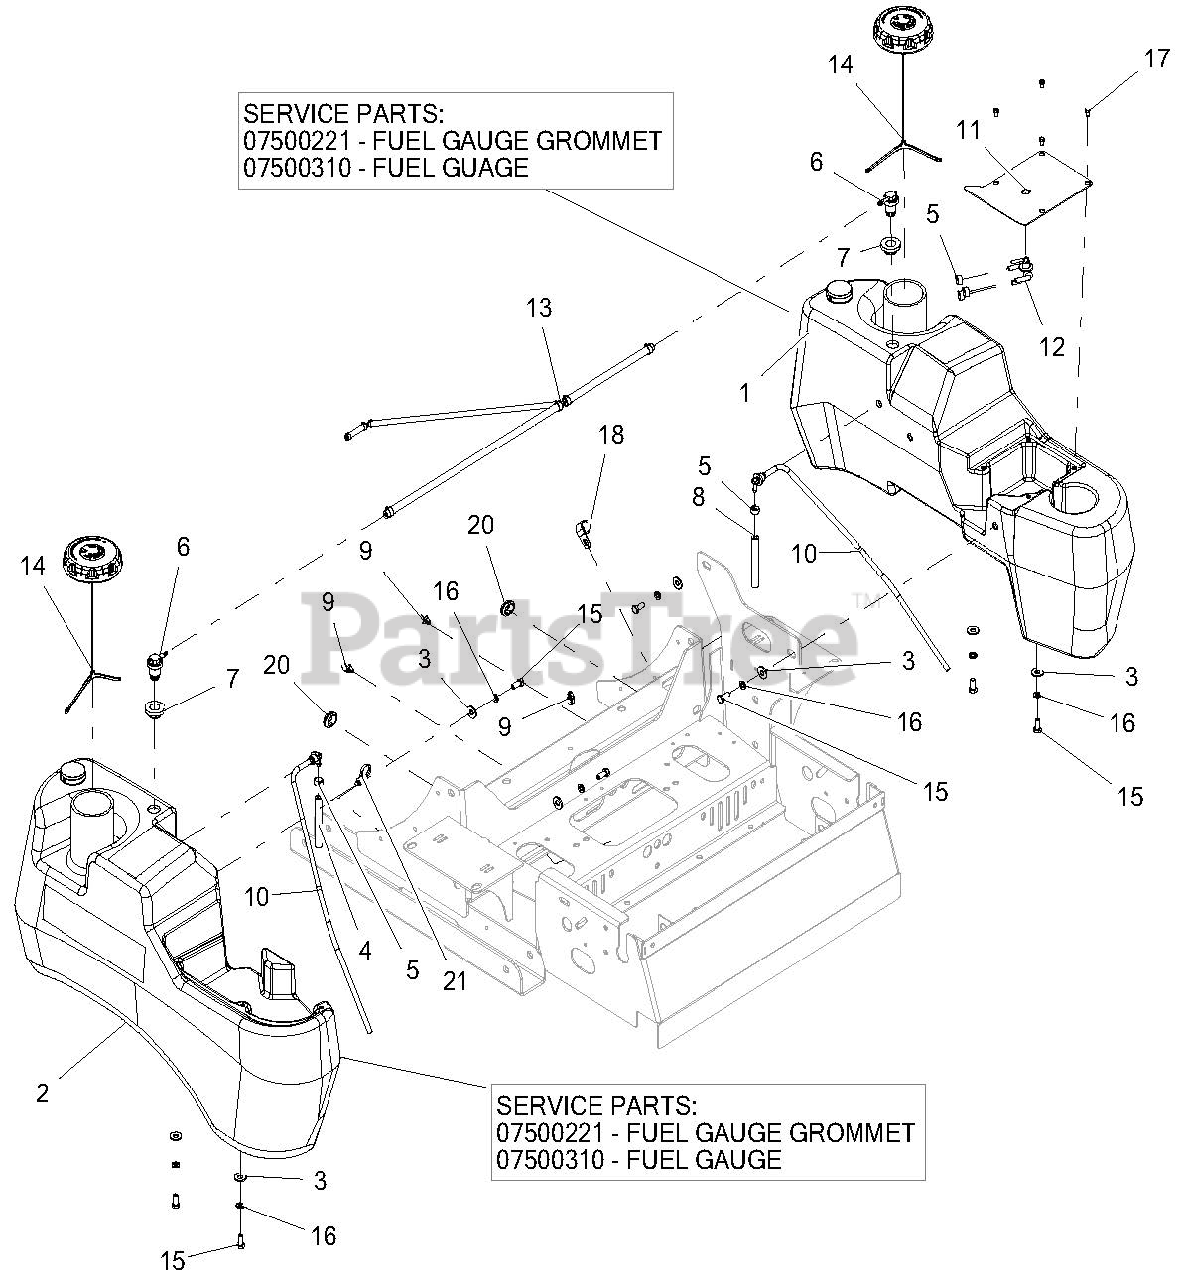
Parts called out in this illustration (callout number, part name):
1	ASSY-LH LARGE FUEL TANK W/MECH GAUGE-GAS
1	FUEL GUAGE GROMMET
1	FUEL GUAGE
2	ASSY-RH LARGE FUEL TANK W/MECH GAUGE-GAS
2	FUEL GUAGE GROMMET
2	FUEL GUAGE
3	WSHR-FL-STL.38X.875X.083 YWZC
4	.25 LOW-PERM GAS HOSE 54.00" LG - RH TANK TO VALVE
5	CLAMP, FUEL LINE
6	VALVE, COMBINATION
7	GROMMET, REMOTE VENT NITRILE
8	.25 LOW-PERM GAS HOSE 19.00" LG - LH TANK TO VALVE
9	CLIP, ROUTING
10	ASM, LARGE TANK FUEL PICKUP
11	PLATE, FUEL VALVE MOUNTING-RED
12	VALVE, FUEL
13	PT400, FUEL LINE ASSEMBLY
14	CAP, FUEL VENT-IN AUTOLOCK
15	BLT-HEX .31-18X.75 GR5 YWZC
16	WSHR-LK .31X.078 REG YWZC
17	SCR-MCH 10-24X.38 HWH STAINLESS
18	CLAMP, CUSHIONED STEEL .75
20	GROMMET, RUBBER
21	CABLE TIE W/ TREE
